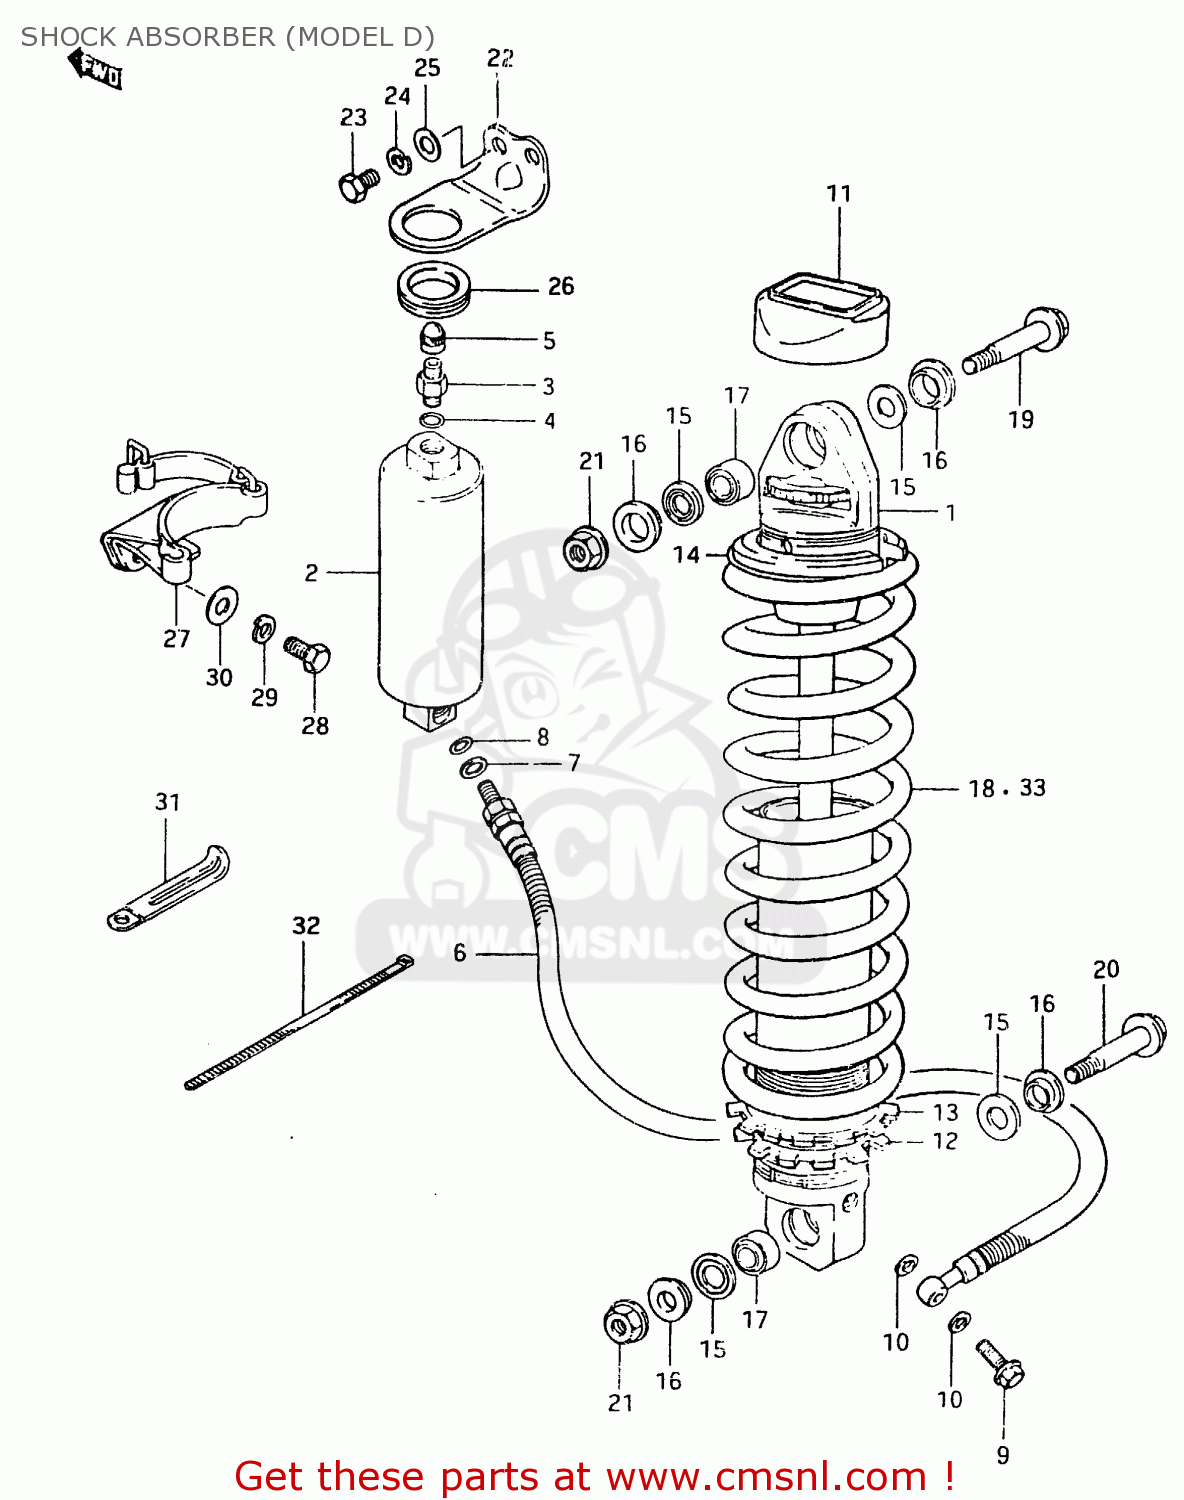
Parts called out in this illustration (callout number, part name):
1	ABSORBER ASSEMBLY,REAR SHOCK
2	RESERVE TANK,REAR SHOCK
3	VALVE,FRONT FORK AIR
4	O-RING
5	CAP
6	HOSE,REAR SHOCK ABSORBER
7	WASHER,REAR SHOCK HOSE
8	O-RING,RESERVE TANK
9	BOLT,REAR SHOCK ABSORBER
10	GASKET (NAS)
11	CAP
12	GUIDE,SPRING
13	SPRING GUIDE
14	GUIDE,REAR SHOCK ABSORBER SPRING
15	DUST SEAL,LWR
16	COLLAR
17	BEARING
18	SPRING
19	BOLT
20	BOLT(10X54)
21	NUT
22	BRACKET,RESERVOIR TANK
23	BOLT
24	LOCK WASHER
25	WASHER
26	CUSHION,RESERVOIR TANK
27	BRACKET,RESERVOIR TANK
28	BOLT, UPPER
29	LOCK WASHER
30	WASHER
31	CLAMP
32	CLAMP
33	SPRING
